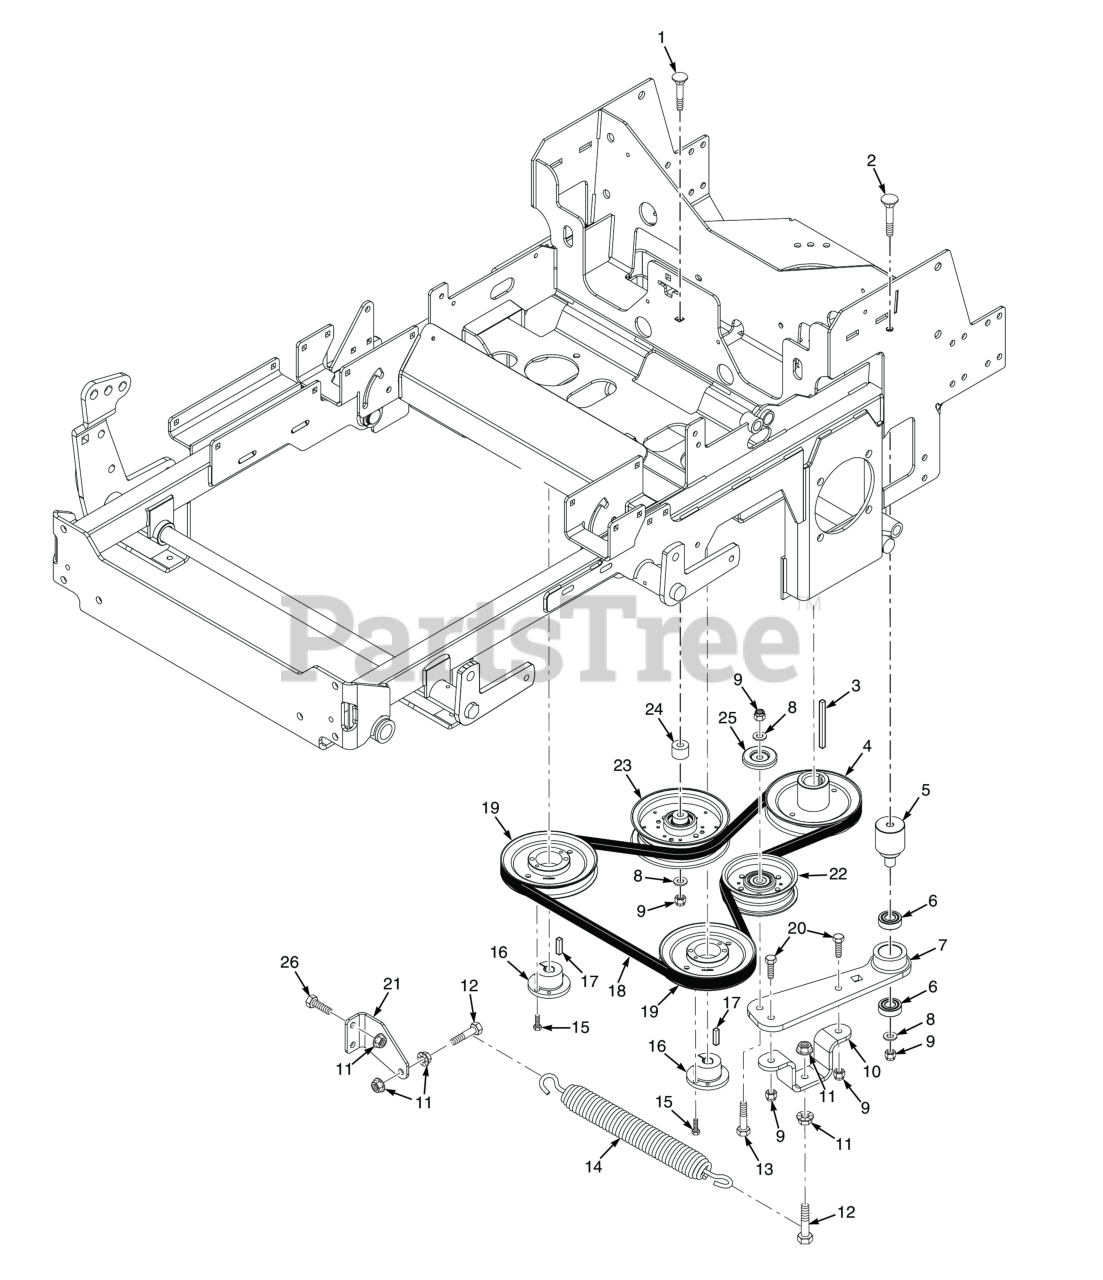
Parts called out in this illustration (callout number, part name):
1	Bolt, Carriage 3/8-16 x 3-1/4"
2	Bolt, Hex Head 3/8-16 x 3-1/2"
3	Key, 1/4 x 1/4 x 3-1/2"
4	Pulley, 5.75" Dia. - 1.125 Bore
5	Pivot, Idler Arm
6	BEARINGS, BALL, NEUTRAL RETURN
7	Idler Arm Assembly
8	Flatwasher, 3/8 (.391 x .938 x .105 HD) Grade 8
9	HEX NUT, ELASTIC STOP LOCK, 3/8-16
10	Mounting Bracket, Idler
11	NUT, 3/8-16 SERRATED FLANGE HEX HEAD
12	Bolt, Hex Head 3/8-16 x 1-1/2" Grade 8 Black
13	Bolt, Hex Head 3/8-16 x 2-1/4" - 61"
14	Spring, Pump Drive
15	Bolt, Hex Head 1/4-20 x 1" Grade 8 Black
16	Hub, Tapered, 15mm Bore
17	KEY, 5 MM X 5 MM X 25 MM
18	Belt, Pump Drive (61")
19	Pulley, 5.75 O.D. (Gasoline Engines)
20	Bolt, Hex Head 3/8-16 x 1-1/4", Kawasaki FX / FT & FT-EFI
21	Bracket, Spring Anchor
22	Pulley, 4" Dia. Idler
23	Idler Pulley, Belt Clutch
24	Spacer, Idler
25	Quick Pin, 5/16" Dia.
26	Carriage Bolt, 3/8-16 x 1.0"
